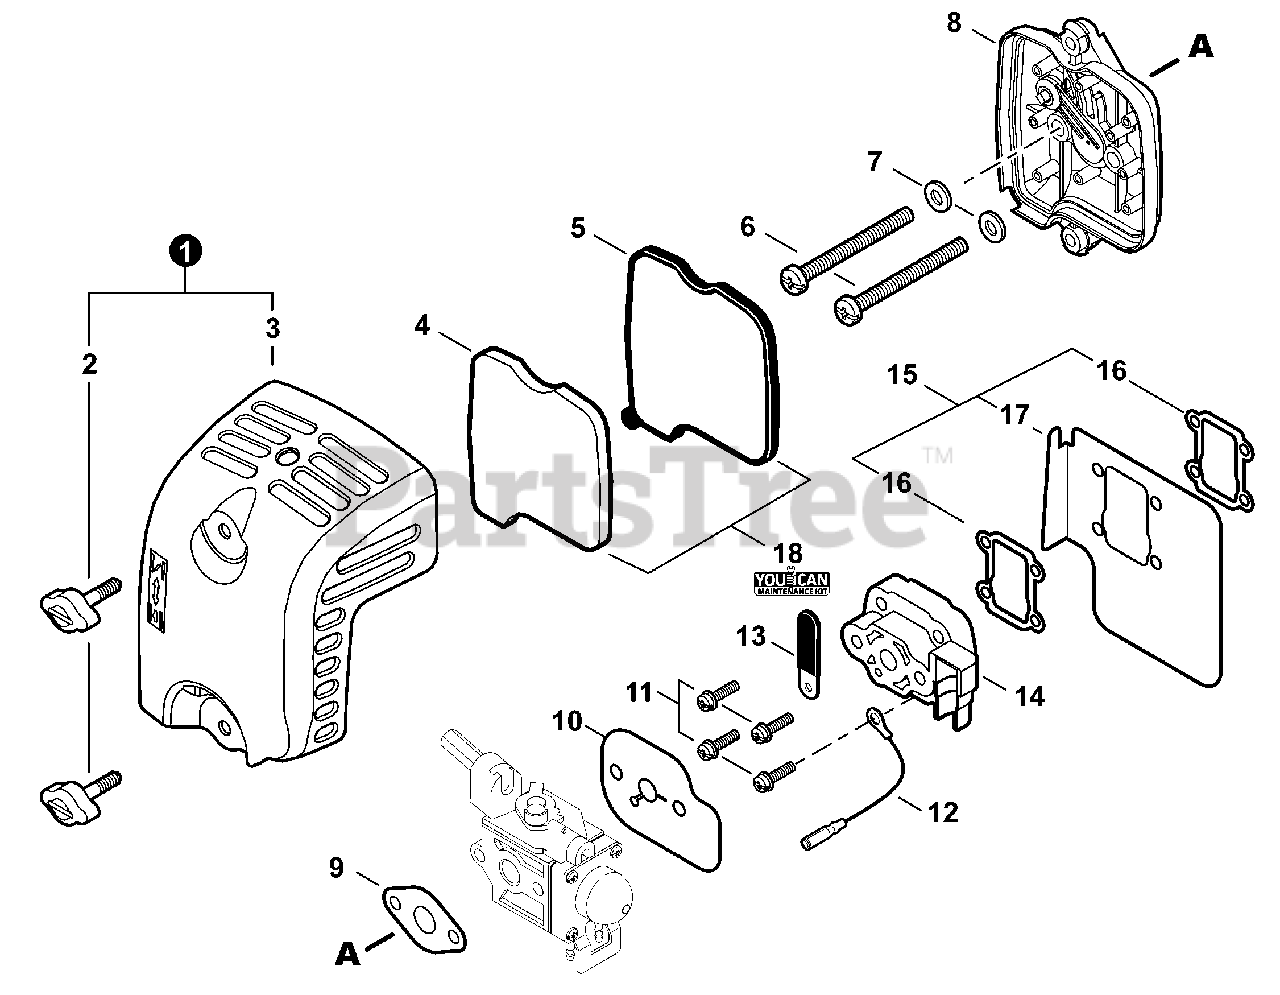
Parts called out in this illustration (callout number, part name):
1	COVER ASSY, AIR FILTER
2	THUMBSCREW
3	COVER, AIR FILTER
4	PRE-FILTER, FOAM
5	FILTER, AIR
6	SCREW M5x60
7	WASHER 5.5x12x0.8
8	CASE, AIR FILTER
9	GASKET, INTAKE
10	GASKET, INTAKE
11	SCREW M5x22
12	LEAD - GROUND L= 110 MM
14	INSULATOR WITH REED VALVE
15	SHIELD ASSY, INTAKE HEAT
16	GASKET, EXHAUST
17	HEAT SHIELD, INTAKE
18	TUNE-UP KIT - YOUCANT
